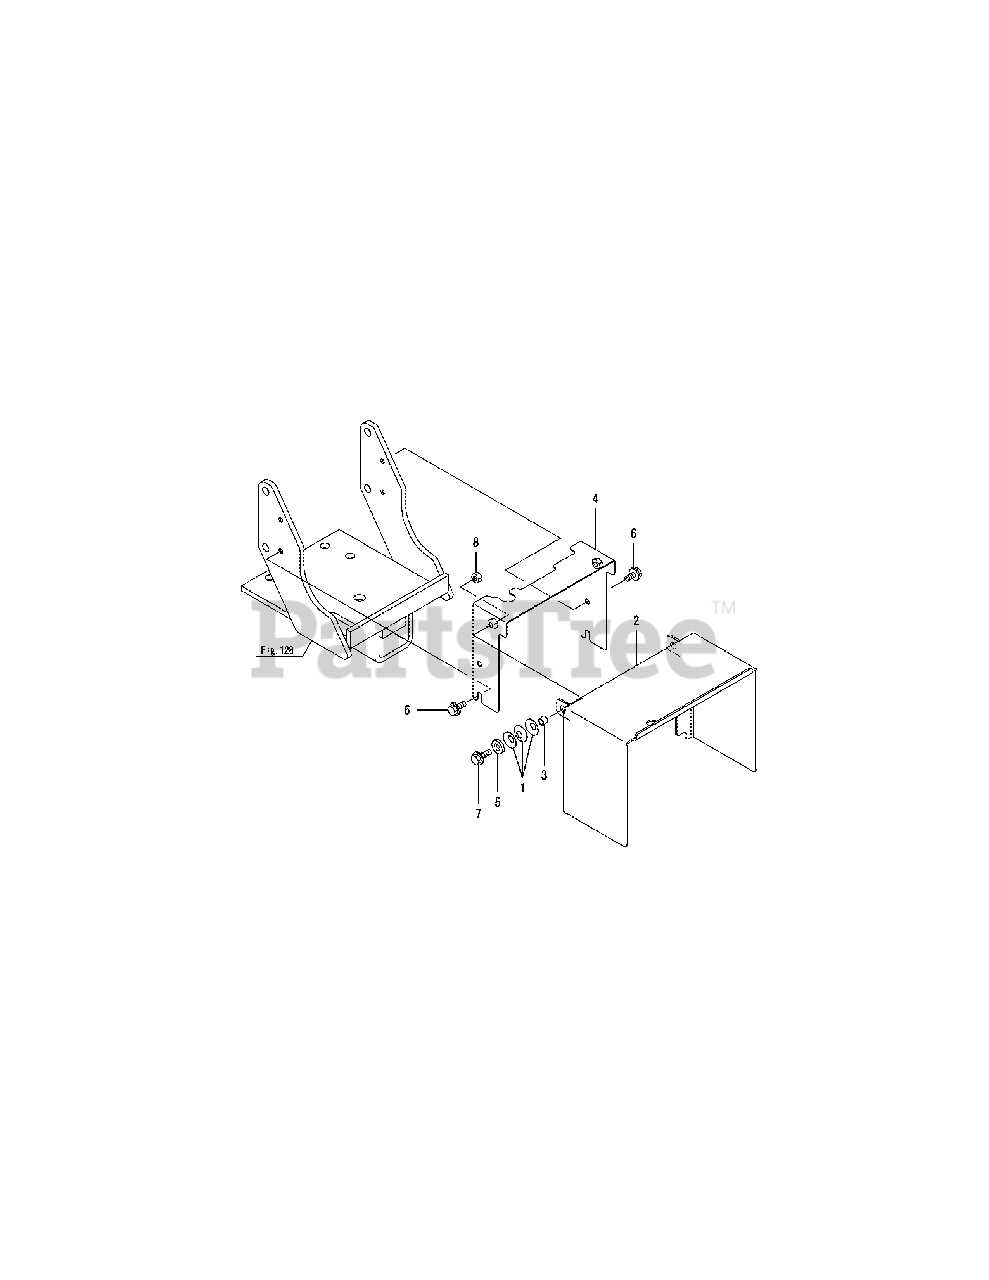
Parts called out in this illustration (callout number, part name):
2	SHIELD M ASSY, PTO
5	WASHER 12,POLISHED
6	BOLT M 8X 16 PLATED
7	BOLT M 8X 25 PLATED
8	LOCK NUT M 8 PLATED
